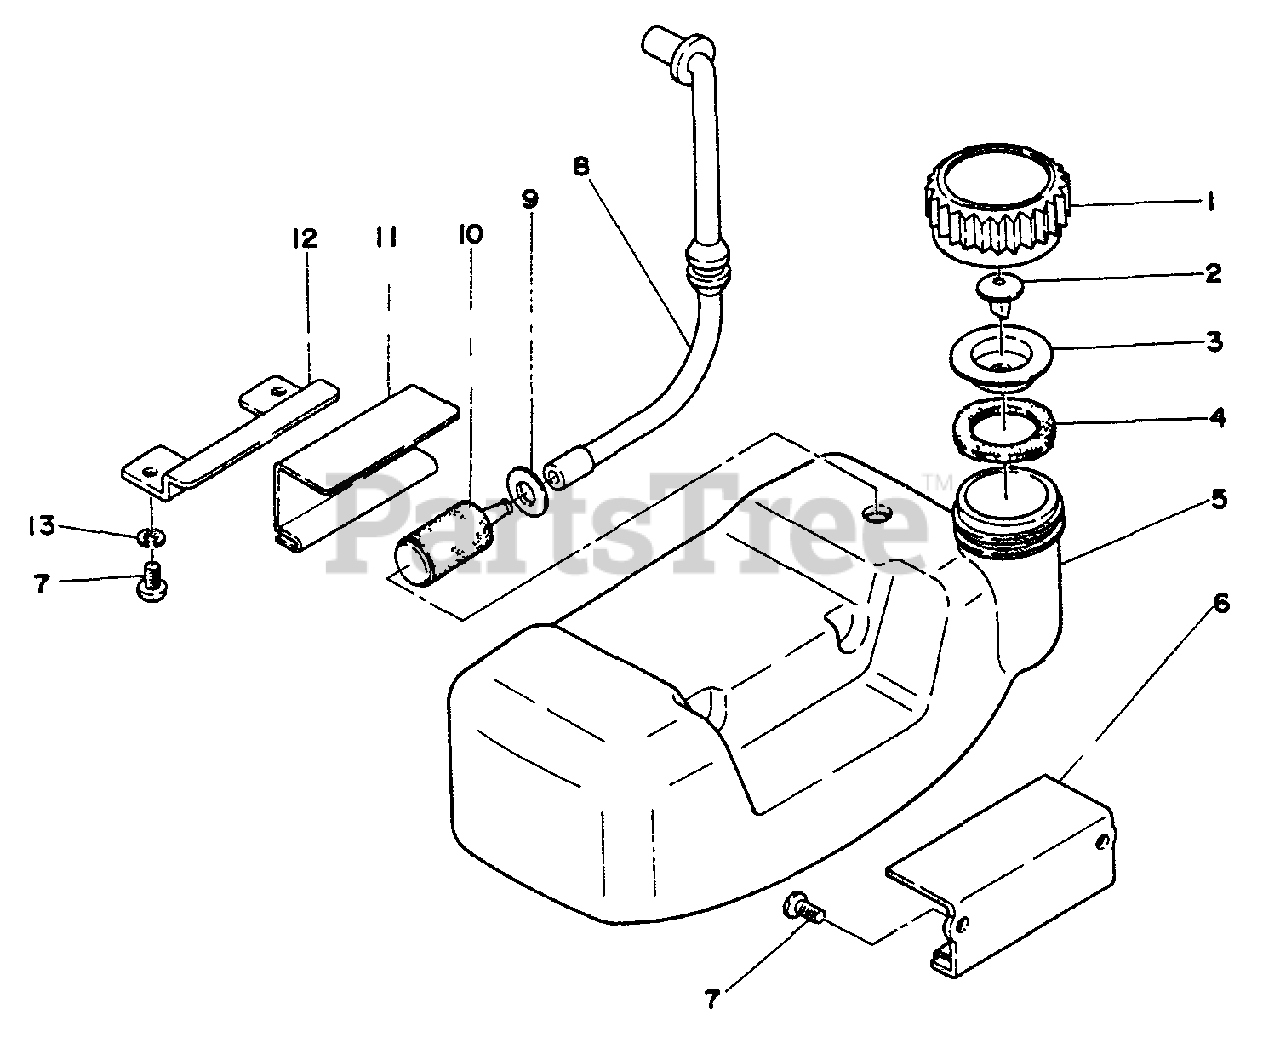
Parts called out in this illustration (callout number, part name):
1	CAP
2	VALVE, CHECK
3	HOLDER, CHECK VALVE
4	GASKET, CAP
5	TANK, FUEL
6	BRACKET, FUEL TANK
7	SCREW 4×8
8	PIPE, FUEL
9	WASHER 6.5×11.5×0.8
10	FILTER, FUEL
11	CUSHION, FUEL TANK
12	BRACKET, FUEL TANK
13	WASHER, SPRING 5
